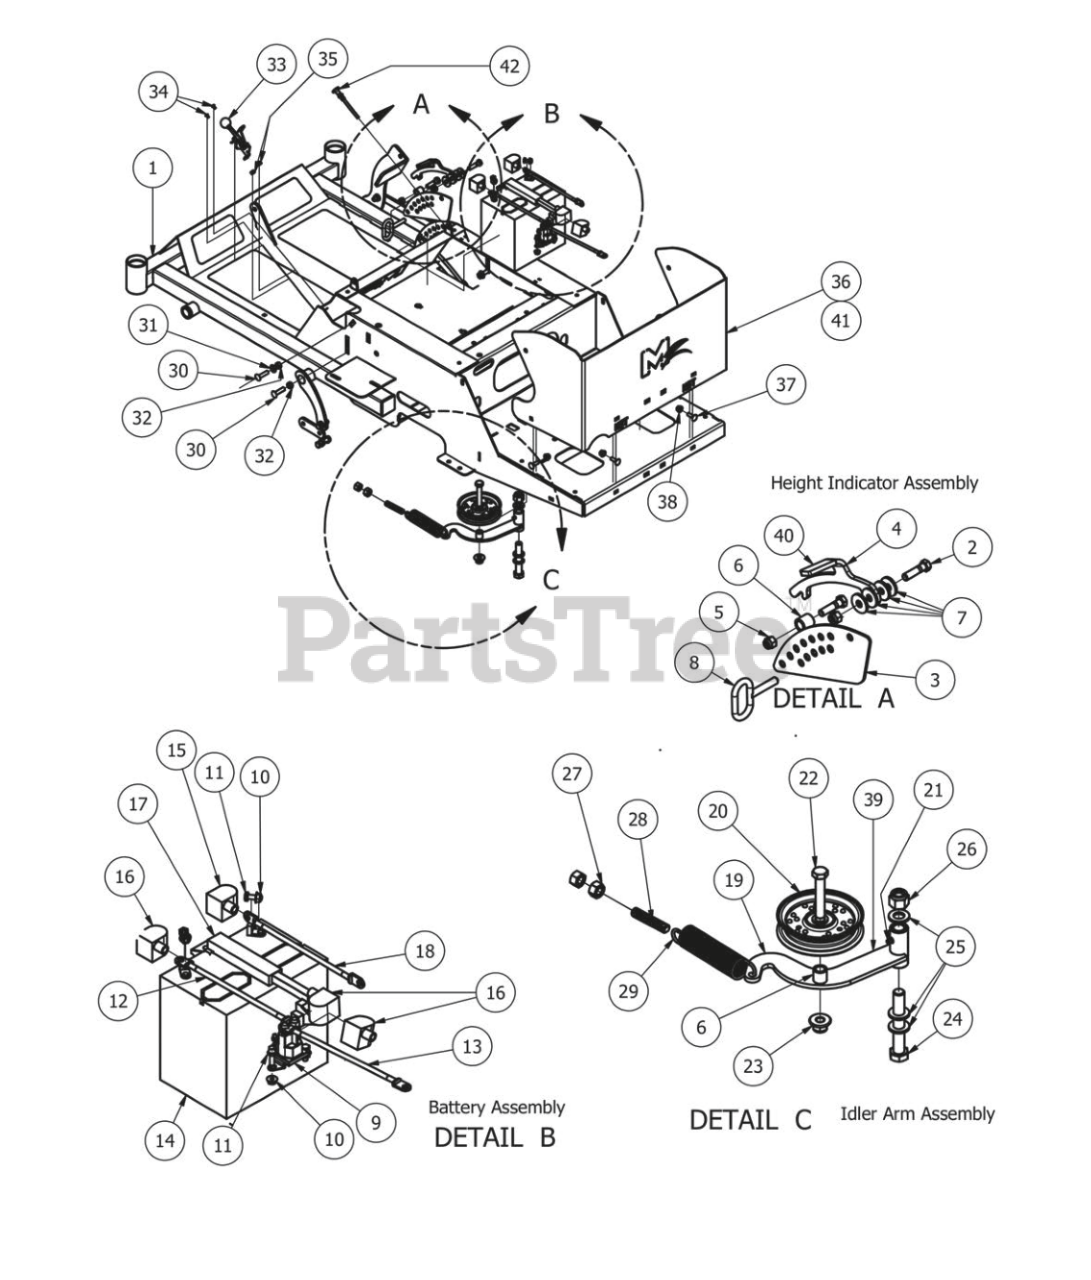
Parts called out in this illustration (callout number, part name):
2	3/8" x 1 1/2" Hex Bolt
3	MZ Height Indicator Plate
4	MZ Deck Level Lock Lever
5	3/8 Nylock Nut
6	3/4 OD x 1/2 ID x 3\4 Length
7	.390 ID Plastic Washer
8	Deck height lever pin
10	1/4-20 Hex Flange Nuts Zinc w/Serrations
11	1/4-20 x 3/4 GR 5 Hex Bolts Zinc
12	10" red battery cable
13	62" red cable
14	MZ Battery
15	Black Boot For ground cable
17	Battery Hold Down
18	24" Ground Cable
19	MZ Idler arm Bracket
20	4-3/4 Idler Pulley
21	1/4" Drive in Grease Fitting
22	1/2" x 2 3/4" Hex Bolt
23	1/2-13 Nylon Flange Nut-Orange
24	5/8" x 4" Hex Bolt
25	.635 ID Plastic Washer
26	5/8 Std NC Nylock Nut
27	1/2" Hex Nut
28	All Thread-pump Idler Tensioner
29	Deck spring big diameter
30	3/8 -16 x 1-1/2 short neck bolt
31	3/8" Flat Washer
32	3/8" Hex Nut
33	Brake cable for MZ
34	10-24 X 5/8 BS C/S 18-8 SS
35	10-24 Nylon Insert Locknut
36	MZ Back Plate
37	5/16" x 1" Carriage Bolt
38	5/16" Flange Nut Zinc W/Serrations
39	Parts 6,19,20,21,22,23 make up the Mz Idler arm assembly
40	Deck Height Handle Grip MZ
41	MZ Engine Rear plate (21hp)
